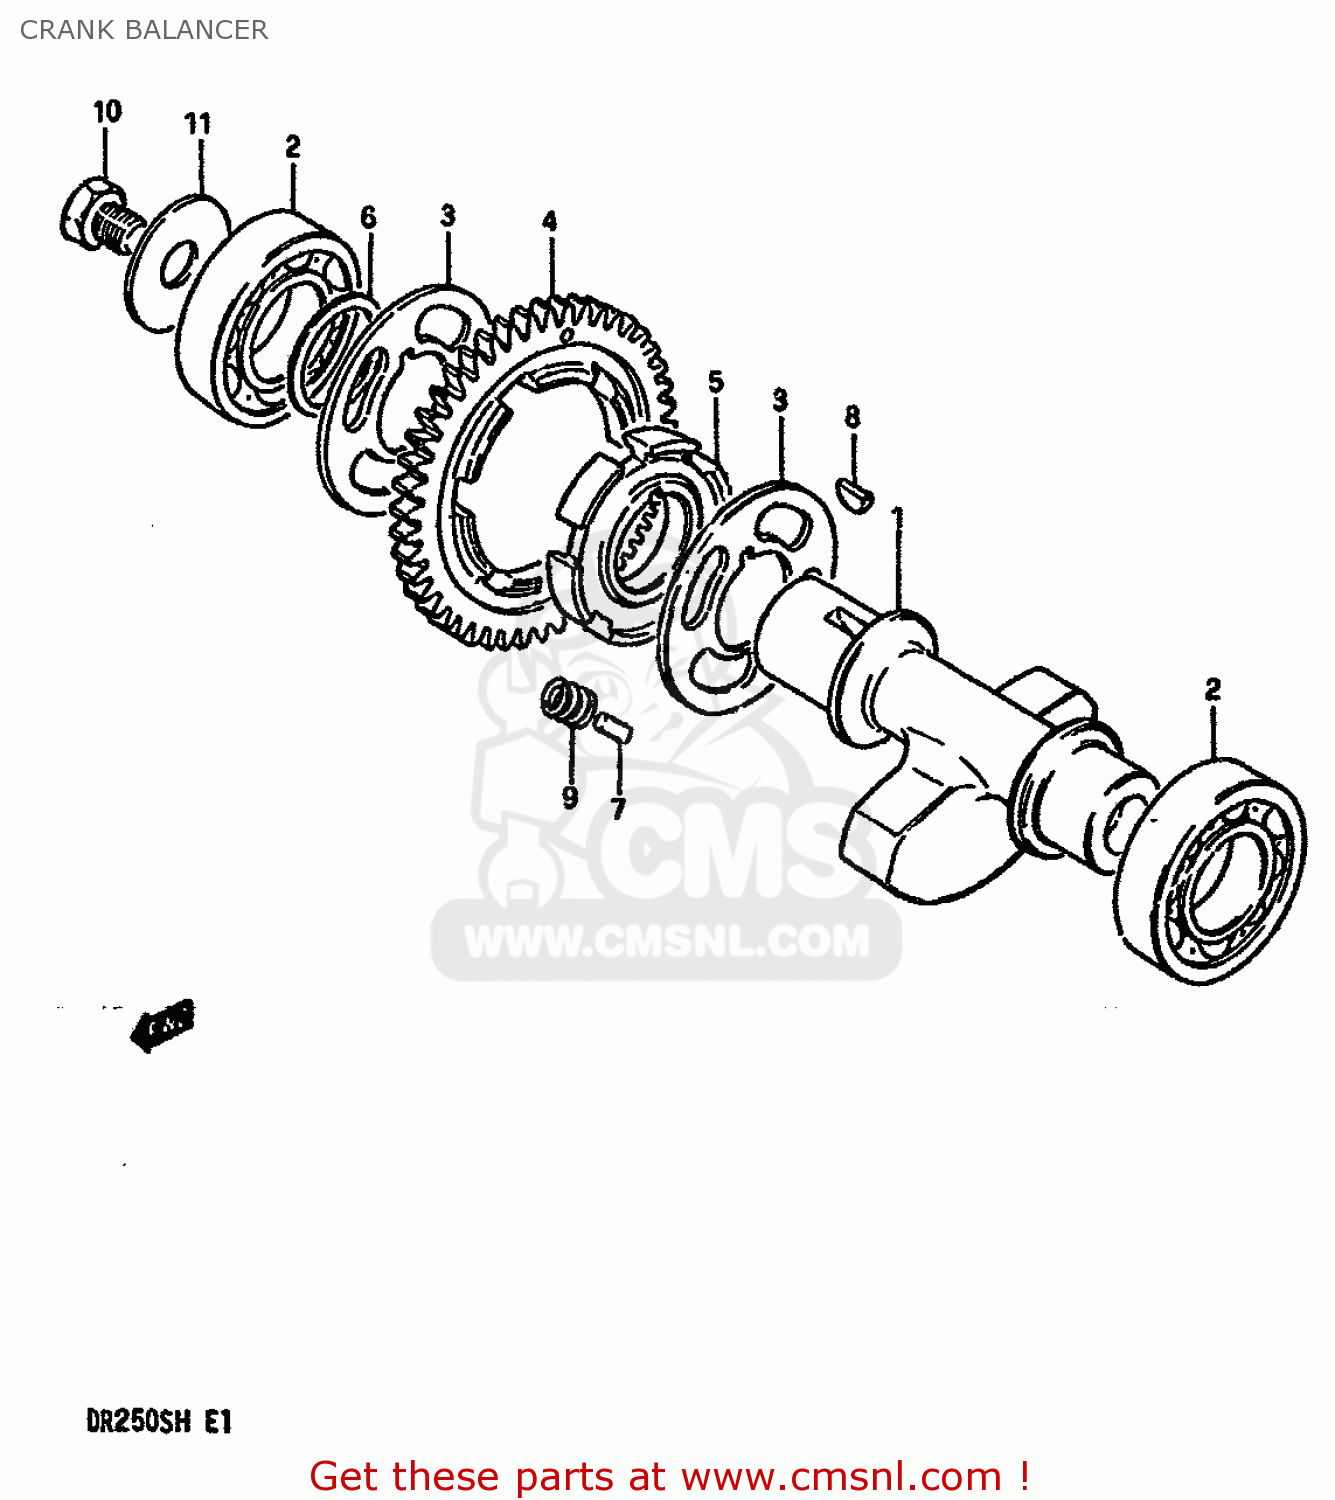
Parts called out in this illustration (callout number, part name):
1	BALANCER,CRANKSHAFT
2	BEARING
3	WASHER
4	GEAR,CRANK BAL DRIVEN(NT:46)
5	RACE,CRK BAL DRIVEN GR INNER
6	SHIM
7	PIN
8	KEY 4MM
9	SPRING
10	BOLT ,12X16
11	WASHER
